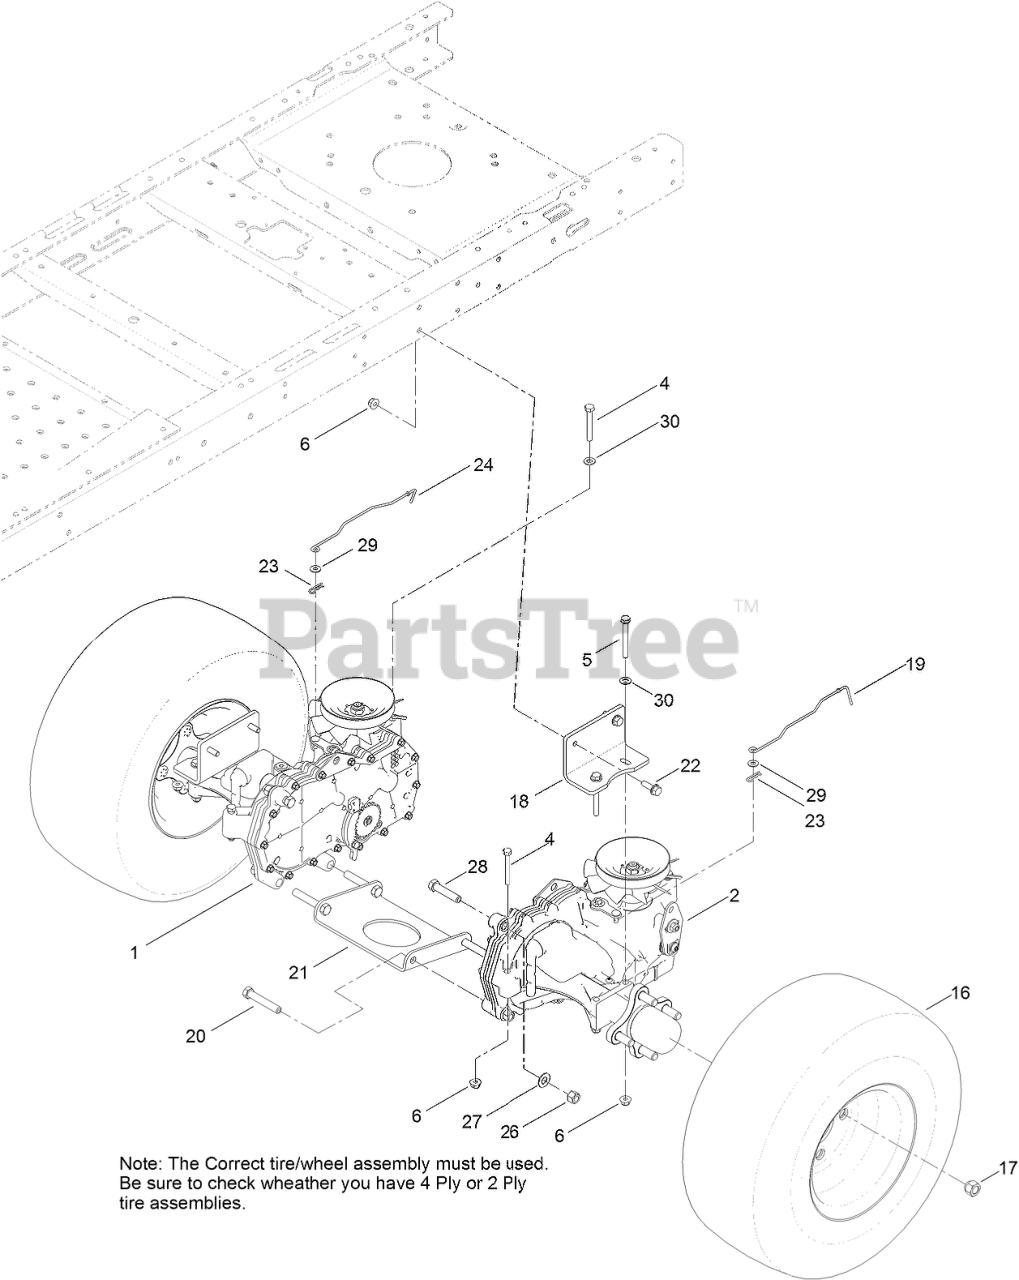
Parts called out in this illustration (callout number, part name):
1	RH HYDRO TRANSAXLE ASM
2	LH HYDRO TRANSAXLE ASM
4	SCREW-HH
5	SCREW-HH
6	NUT-HF, NI
16	4 PLY WHEEL AND TIRE ASM
16	2 PLY WHEEL AND TIRE ASM
17	NUT-LUG
18	MOUNT-HYDRO
19	ROD-BYPASS, LH
20	SCREW-HH
21	PLATE-CROSS, HYDRO
22	SCREW-HHF
23	PIN-COTTER
24	ROD-BYPASS, RH
26	NUT-LOCK, NI
27	WASHER-FLAT
28	SCREW-HH
29	WASHER
30	WASHER-PLAIN
